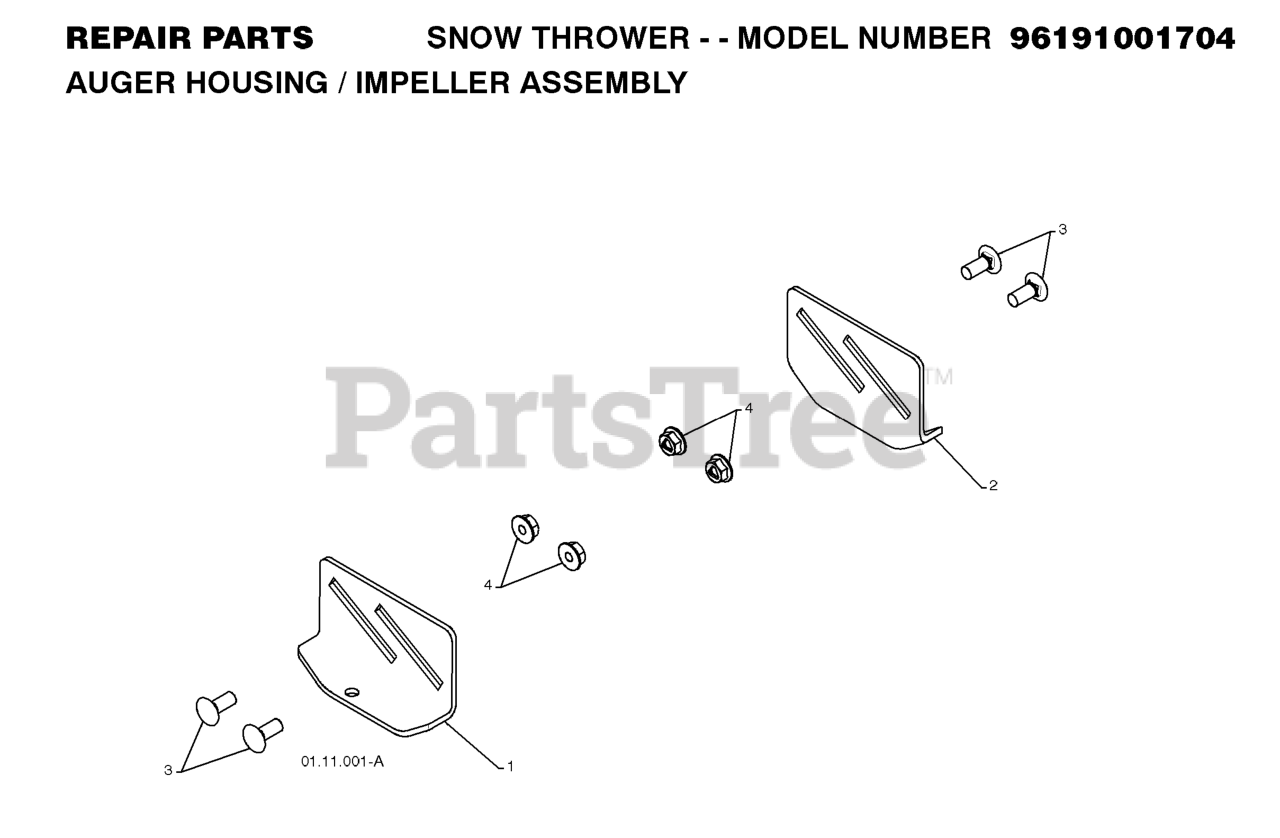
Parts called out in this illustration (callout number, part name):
1	SKID PLATE LH
2	SKID PLATE RH
3	BOLT
4	NUT.LOCK.5/16-18
